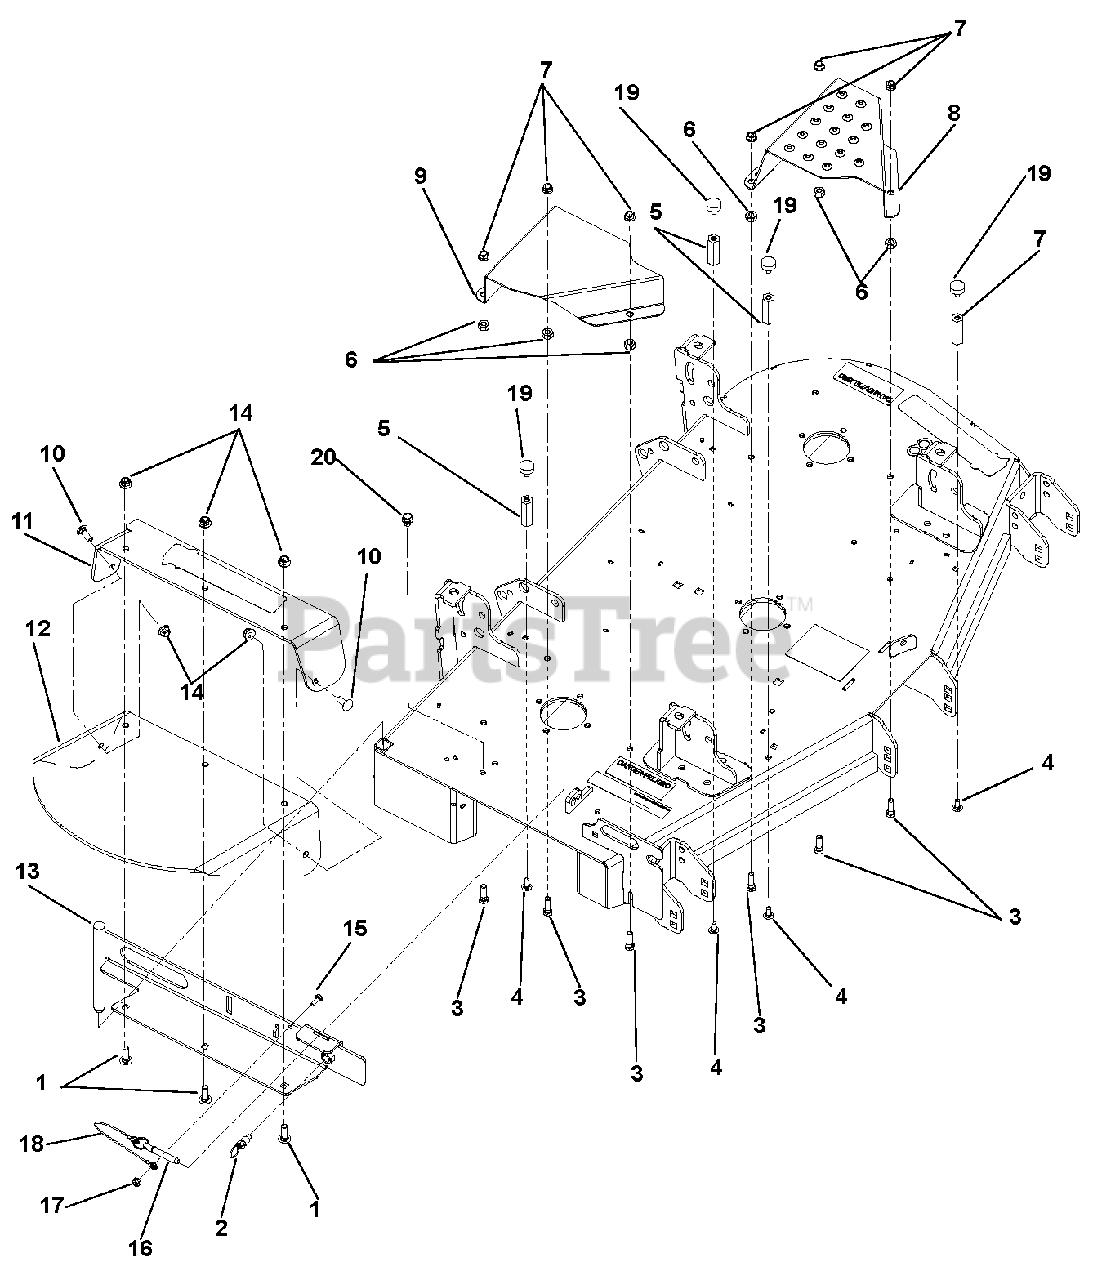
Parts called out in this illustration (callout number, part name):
1	Bolt, Round Head Square Neck .38-16 x 1.25
2	Pull Pin
3	Bolt, Hex .38-16 x 1.25
4	Bolt, Round Head Square Neck .31-18 x .75
5	Nut, Coupling .31-18 x 3.00
6	Nut, Heavy Hex .38-16
7	Nut, Flange .375-16
8	Guard, Left Hand Deck Belt, 44 – 52 (991079, 080, 095, 096)
9	Guard, Right Hand Spindle Sheave, 44 – 52 (991079, 095)
10	Bolt, Round Head Square Neck .38-16 x 1.00
11	Rubber Discharge Chute Support
12	Chute, Rubber Discharge
13	Weldment, Discharge Chute Support, 48" (991079, 095)
14	Nut, .38-16 Nyloc Flange
15	Bolt, Hex .25-20 x .75 (991079, 095)
16	Pin, Spring Ball .375OD x 1.50 (991079, 095)
17	Nut, Locking Top Flange .25-20 (991079, 095)
18	Cable, 6.0 Lanyard, Nylon (991079, 095)
19	Bumper, Rubber
20	Screw, Self Tapping .38-16 x .50
